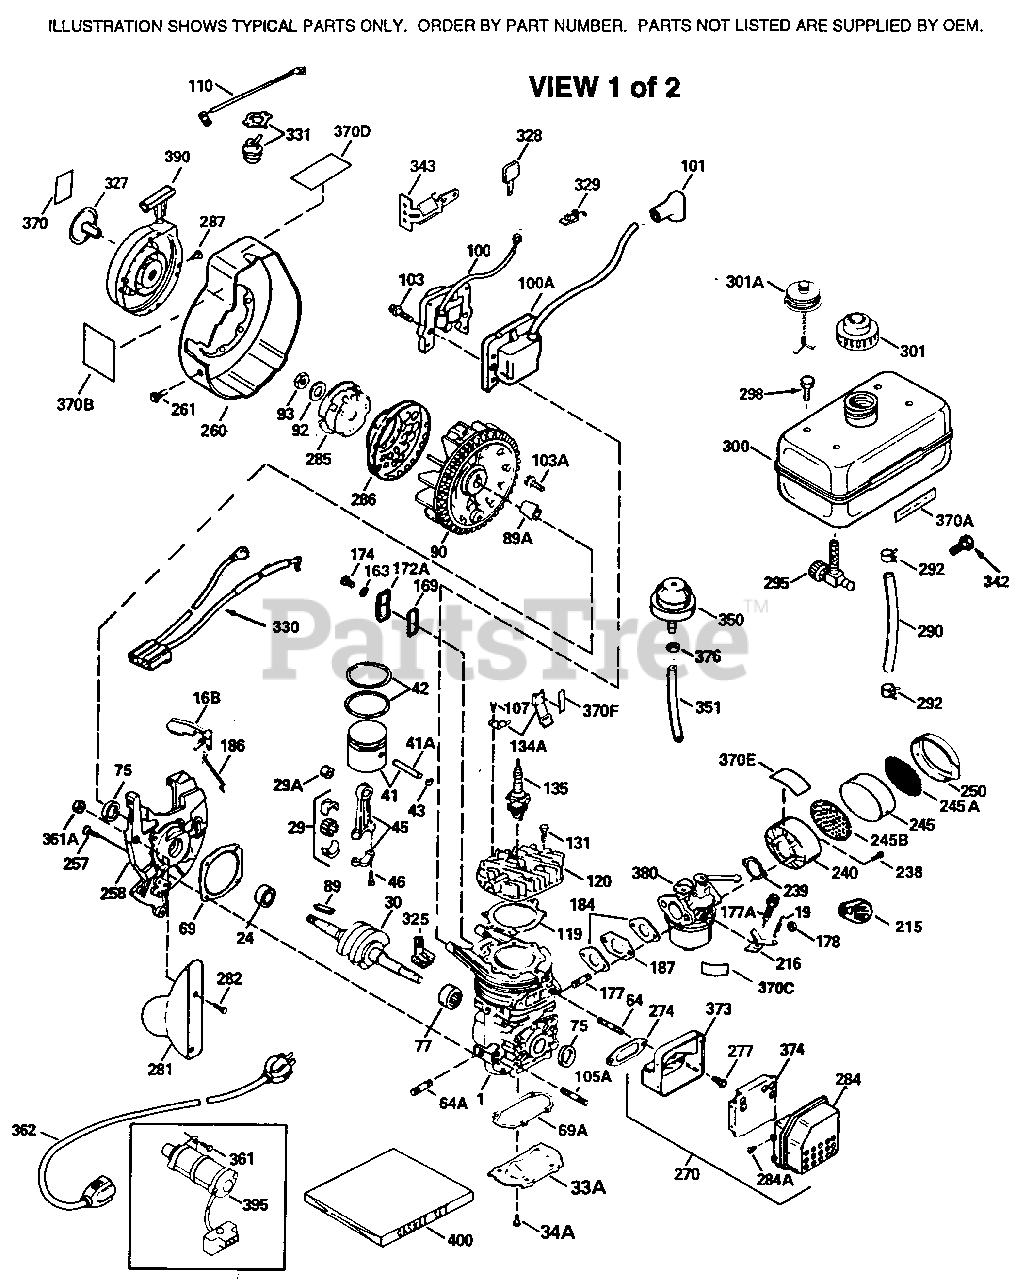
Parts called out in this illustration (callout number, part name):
1	"Cylinder Order S/B if replacement isn eeded
16B	Air Vane
19	Extension Spring
24	Ball Bearing
29	Needle Bearing & Liner Set 37 Needles
29A	Cartridge Bearing
30	Crankshaft
33A	Cover Plate
41	Piston & Pin Ass'y. (Incl. 43)
42	Ring Set
43	Piston Pin Retaining Ring
45	Connecting Rod Ass'y. Incl. 29, 29A,& 46
46	Connecting Rod Bolt
69	* Cylinder Cover Gasket
69A	* Cover Plate Gasket
75	Oil Seal
77	Cartridge Bearing
89A	Adapter Sleeve
90	Flywheel
92	Belleville Washer
93	Flywheel Nut
100	Solid State Ignition (Incl. 101)
101	Spark Plug Cover
103	Screw, Torx T-15, 10-24 x 1"
119	* Cylinder Head Gasket
120	Cylinder Head
130B	Screw, 1/4-20 x 1/2"
135	Resistor Spark Plug (RCJ8Y)
169	* Compression Release Cover Gasket
172A	Compression Release Cover
177	Screw, 5/32 Allen, 1/4-20 x 1"
184	* Carburetor Gasket
186	Governor Link
209	Screw, Torx T-25, 10-24 x 1/2"
216	R.P.M. Adjusting Lever
257	Screw, Torx T-30, 1/4-20 x 5/8"
258	Blower Housing Base (Incl. 75)
260	Blower Housing
274	* Exhaust Gasket
277	Screw, 1/4-20 x 2-3/4"
285	Starter Cup
287	Screw, 8-32 x 21/64"
300	Fuel Tank
301	Fuel Cap
325	Wire Clip
330	Wire Harness
350	Primer Ass'y.
351	Primer Line
353A	Screw, Torx T-30, 1/4-20 x 3/4"
380	Carburetor (Incl. 184)
390	Rewind Starter
400	* Gasket Set (Incl. items marked PK in notes) Incl. (1) each of part Nos.51 0207A, 510274A, 510292A, 510323A,5103 25A, 510326A, 510346A, and (2) ofpart # 510110A
